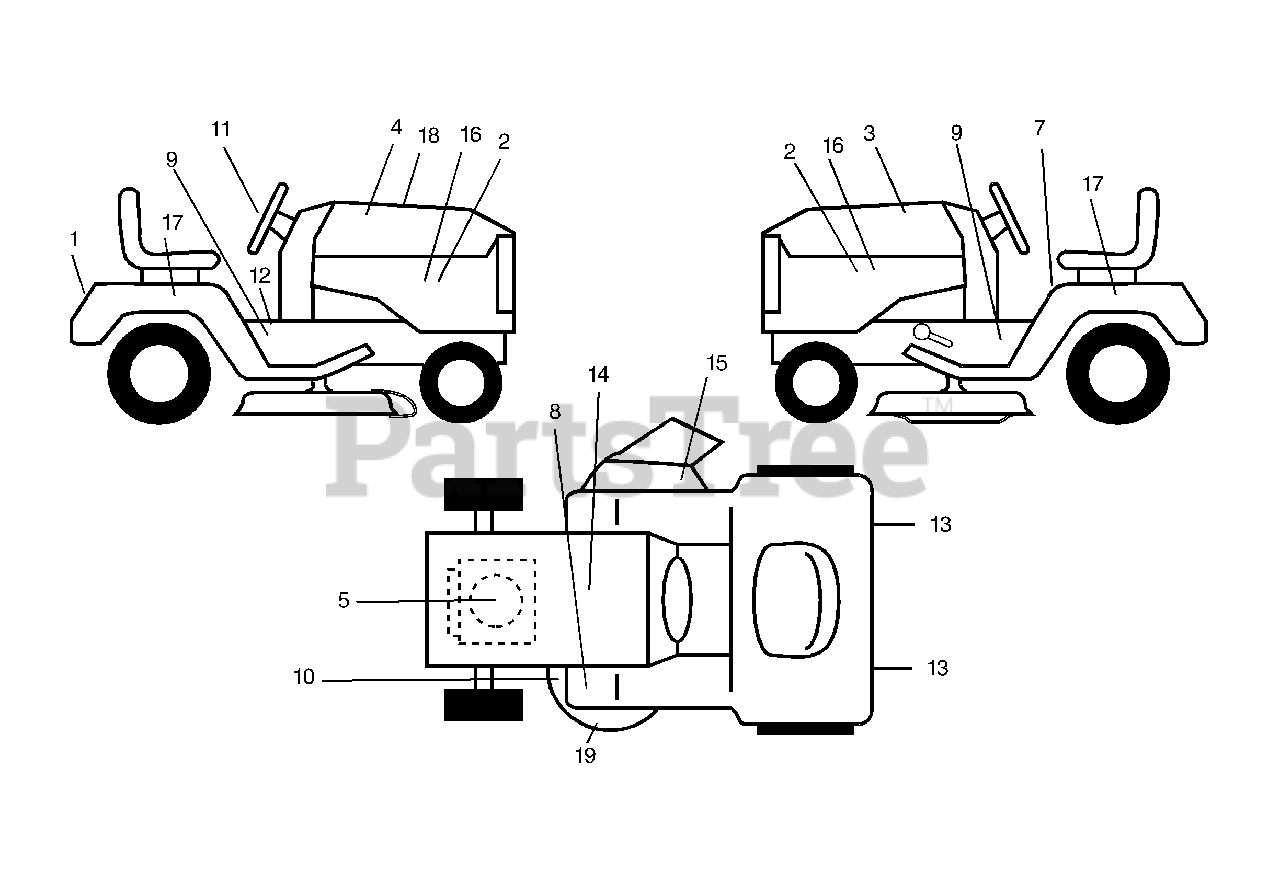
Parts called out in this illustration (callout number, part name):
1	Decal Fender
2	Decal Side Panel
3	Decal Hood LH
4	Decal Hood RH
5	Decal HP Engine
7	Decal Danger Fender English/French
8	Decal Clutch/brake English/French
9	Decal Chassis
10	Decal V-Belt Sch
11	Decal Steering
12	Decal Oper s DL Eng/Fr
13	Reflector Taillight
14	Decal, Btry Dngr/Psn
15	Decal, Warning Mower
16	Decal Panel
17	Decal Fender Side
18	Decal Replacement Hood
19	Decal Deck Mulch/Vented
